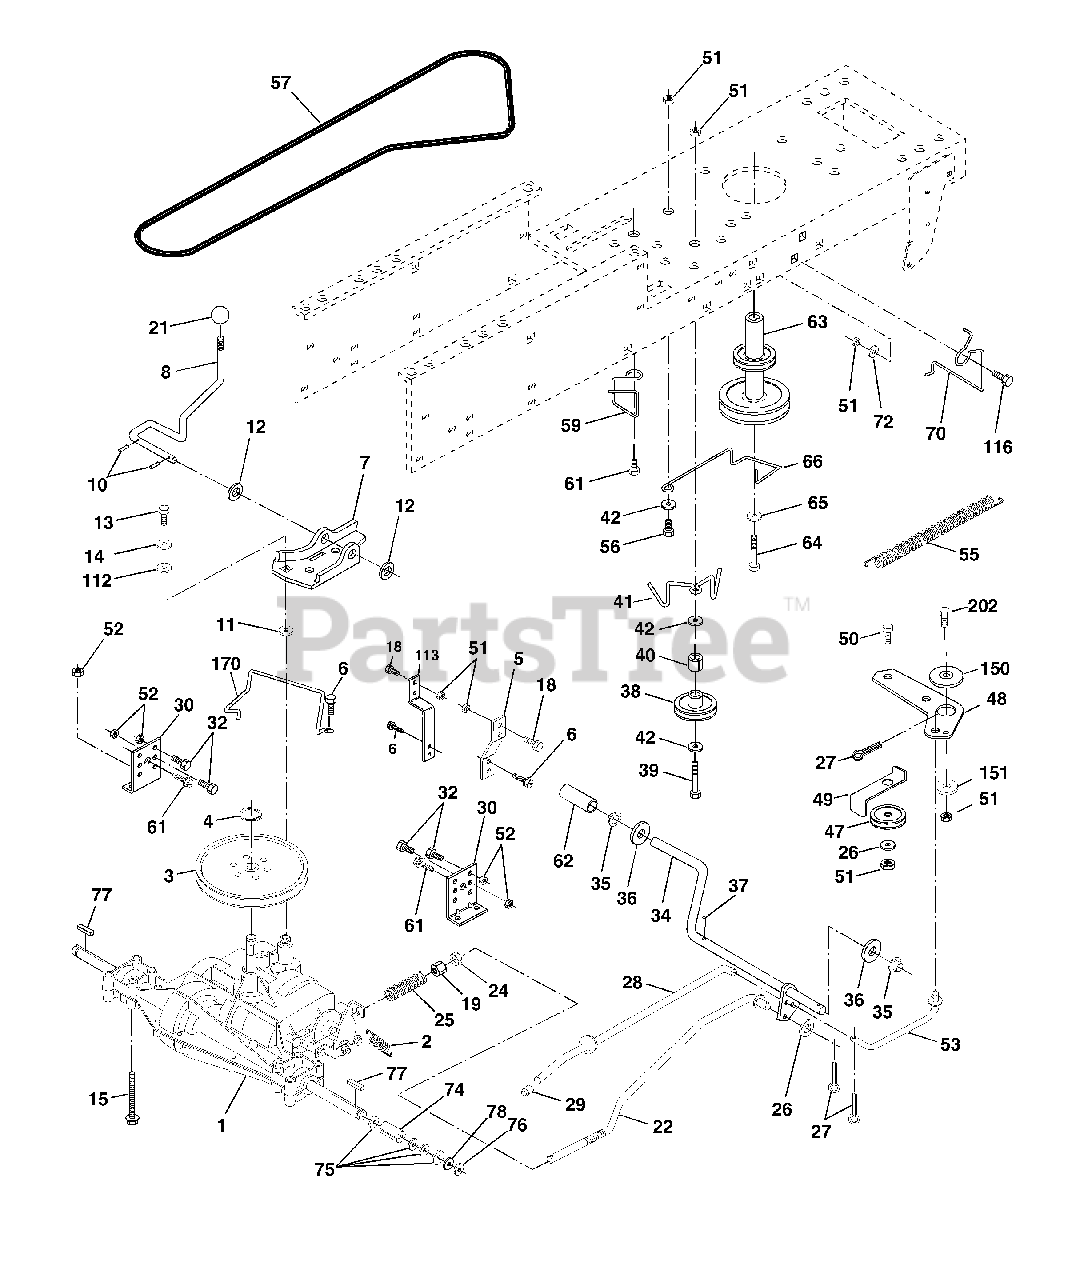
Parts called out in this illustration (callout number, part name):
2	Spring Extension Brake
3	Pulley Transaxle 18" tires
4	Ring Retainer # 5100-62
5	Strap Torque Rh Pnt Blk
6	Screw 5/16-18 X 3/4
7	Bracket T/A Saddle Shift
8	Rod Shifter Black(dana)
10	Pin
11	Washer Plate Shf 388 Sq Hole
12	Washer 15/32 X 3/4 X 16ga
13	Bolt 1/4-28 UNF Gr. 8 W/Patch
14	Washer
15	Bolt Hex Flghd 5/16-18 x Gr. 5
18	Bolt Fin Hex 3/8-16 UNC x 1 Gr. 5
19	Nut
21	Knob Rd 1/2-13 Plstc Thds Blk
22	Rod Brake Lt
24	Nut
25	Spring Rod Brake 2 00 Zinc
26	Washer
27	Pin
28	Rod Brake Parking Lt/Yt
29	Cap Parking Brake
30	Bracket Transmission
32	Bolt
34	Shaft Asm Pedal Foot
35	Bearing Nylon Blk 629 Id
36	Washer
37	Roll Pin
38	Pulley Idler Flat
39	Bolt Fin Hex 3/8-16 Unc x 2-3/4
40	Spacer Split 395 X 59 Bzp
41	Keeper Belt Idler
42	Washer 13/32 X 13/16 X 12 Ga
47	Pulley Idler V Groove Plastic
48	Bellcrank Clutch
49	Retainer Belt Style Spring
50	Bolt
51	Nut
52	Nut
53	Link Clutch 7 66
55	Spring Return Clutch 6 75
56	Bolt
57	V-belt Ground Drive
59	Keeper Belt Chassis Span Ctr.
61	Screw 3/8-16x3/4
62	Cover Pedal Blk Round
63	Pulley Engine
64	Bolt, Hex 7/16-20 x 4 Grade 5
65	Washer, Lock, Hvy Hlcl Spring 7/16
66	Keeper Belt Engine Flproof
70	Guide Belt Dr Mower Rh
72	Washer 13/32 X 1-1/4 X 12 Ga
74	Spacer Split
75	Washer 25/32 X 1 1/4 X 16 Ga
76	E Ring
77	Key Square 2 0 X 1845/ 1865
78	Washer 25/32 X 1 5/8 X 16ga
112	Washer 9/32 X 3/4 X 10 Ga
113	Strap Torque Lh
116	Bolt, Rdhd Sqnk 3/8-16 x 1.25
150	Bushing Bellcrank
151	Washer 13/32 x 2 x 10 Ga.
170	Keeper Belt Transaxle PMST/Dana
202	Bolt Carr. Sh. 3/8-16 x 1-1/2 Gr. 5
